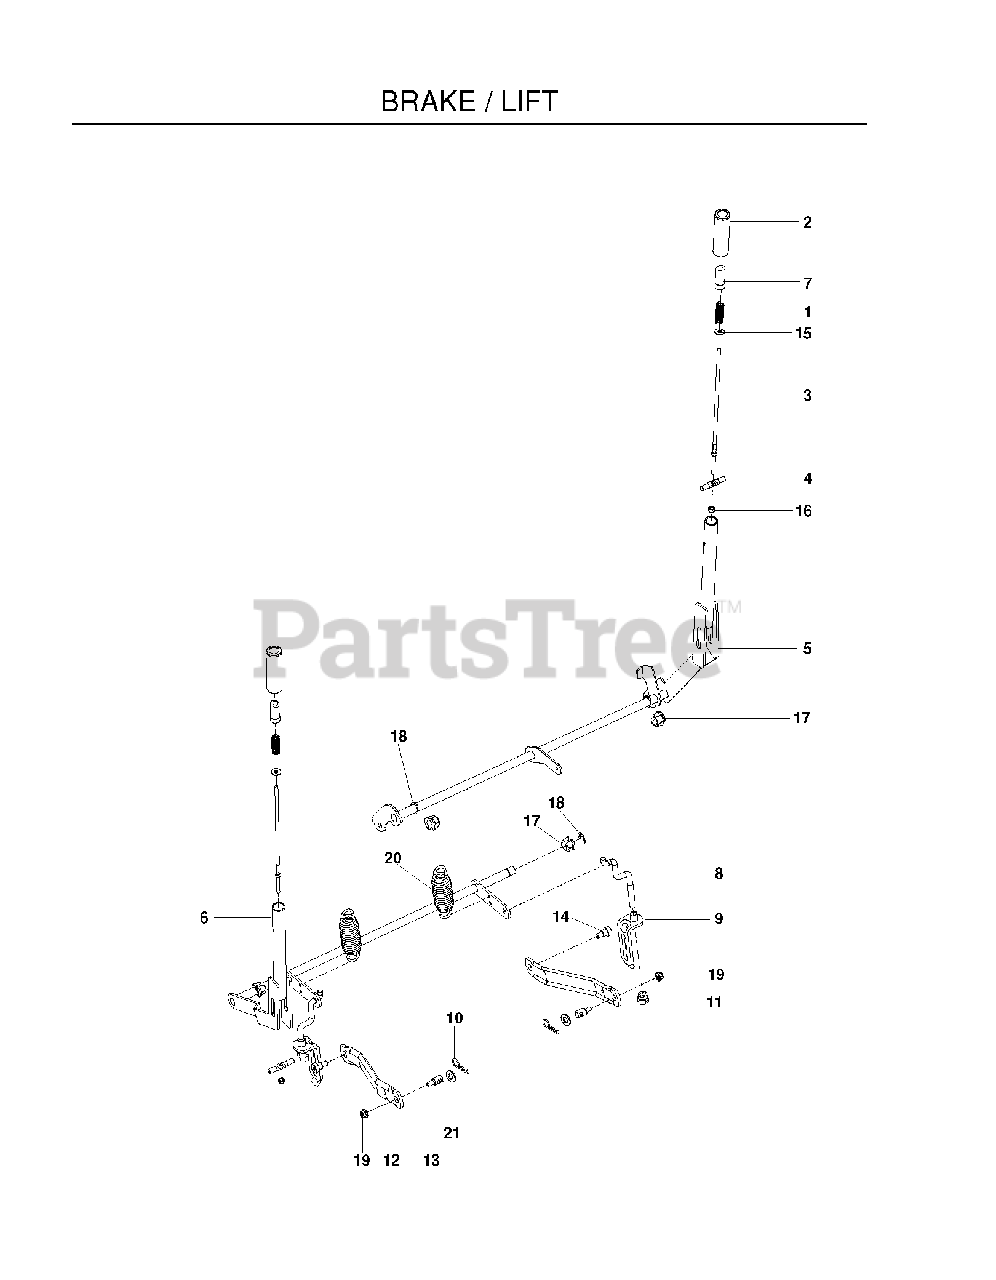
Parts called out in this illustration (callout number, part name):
1	SPRING, COMPRESSION
2	GRIP, HANDLE, BLACK
3	ROD, HANDLE RELEASE
4	ROD, LATCH RELEASE
5	SHAFT.ASSY.BRAKE.WLDMT.BLACK
6	SHAFT, LIFT, BLK
7	BUTTON, PUSH, BLACK (2 2)
8	LINK, REAR SUSPENSION
9	ASSEMBLY, BRKT LINK
10	HAIRPIN #4
11	NUT, LIFT LINK 7/16-20
12	ARM.SUSPENSION.MOWER
13	STUD.FASTNER.W/ANTI-ROTATE
14	SB 3/8-16 X 3/8 SKT HD ZD
15	WASHER 1/4 FLAT
16	NUT 1/4-20 NYLOC
17	PLASTIC NUT
18	E-RING 5/8
19	5/16-18 NYLOC FLANGE NUT
21	WASHER 5/8 FLAT
